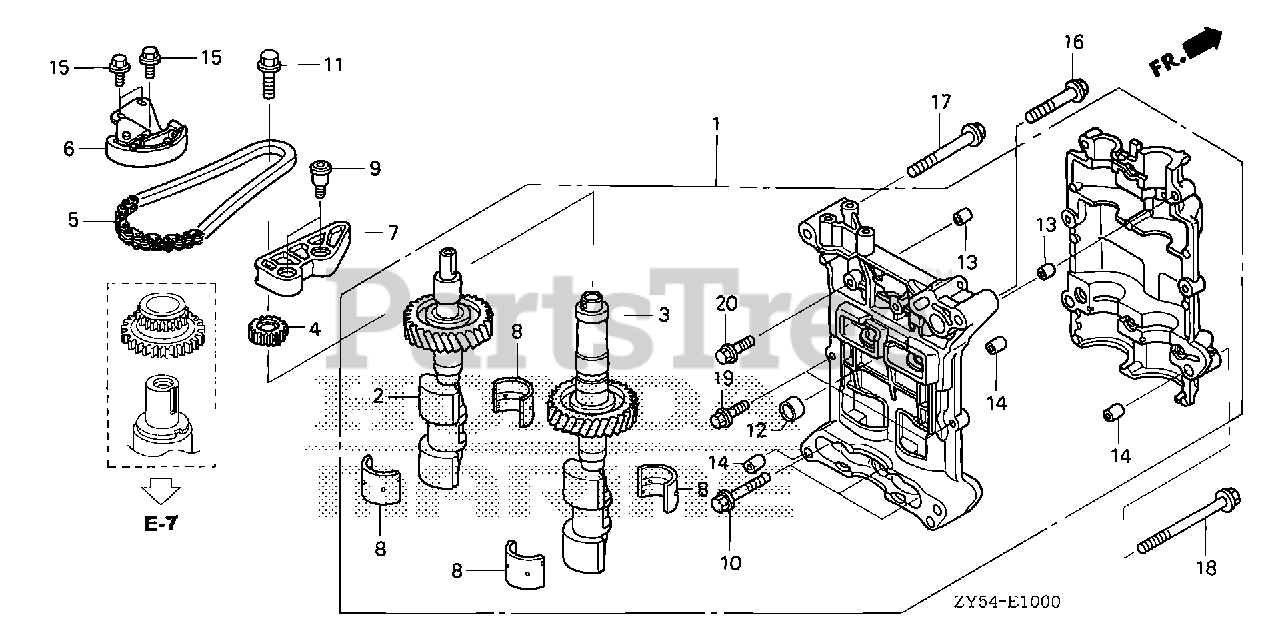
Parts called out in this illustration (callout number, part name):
1	CASE ASSY., BALANCER HOLDER
2	SHAFT, FR. BALANCER
3	SHAFT, RR. BALANCER (NOT AVAILABLE)
3	SHAFT, RR. BALANCER
4	SPROCKET, DRIVEN (17T)
5	CHAIN (62L)
6	TENSIONER, BALANCER SHAFT CHAIN
7	GUIDE, BALANCER SHAFT CHAIN
8	METAL, BALANCER SHAFT (DAIDO)
9	BOLT, CHAIN GUIDE
10	BOLT, FLANGE (8X55)
11	BOLT-WASHER (10X30)
12	PIN, DOWEL (18X13)
13	PIN, DOWEL (8X10)
14	PIN A, DOWEL (12X16)
15	BOLT, FLANGE (6X14)
16	BOLT, FLANGE (8X50)
17	BOLT, FLANGE (8X75)
18	BOLT, FLANGE (10X105)
19	BOLT, FLANGE (6X25)
20	BOLT, FLANGE (6X32)
